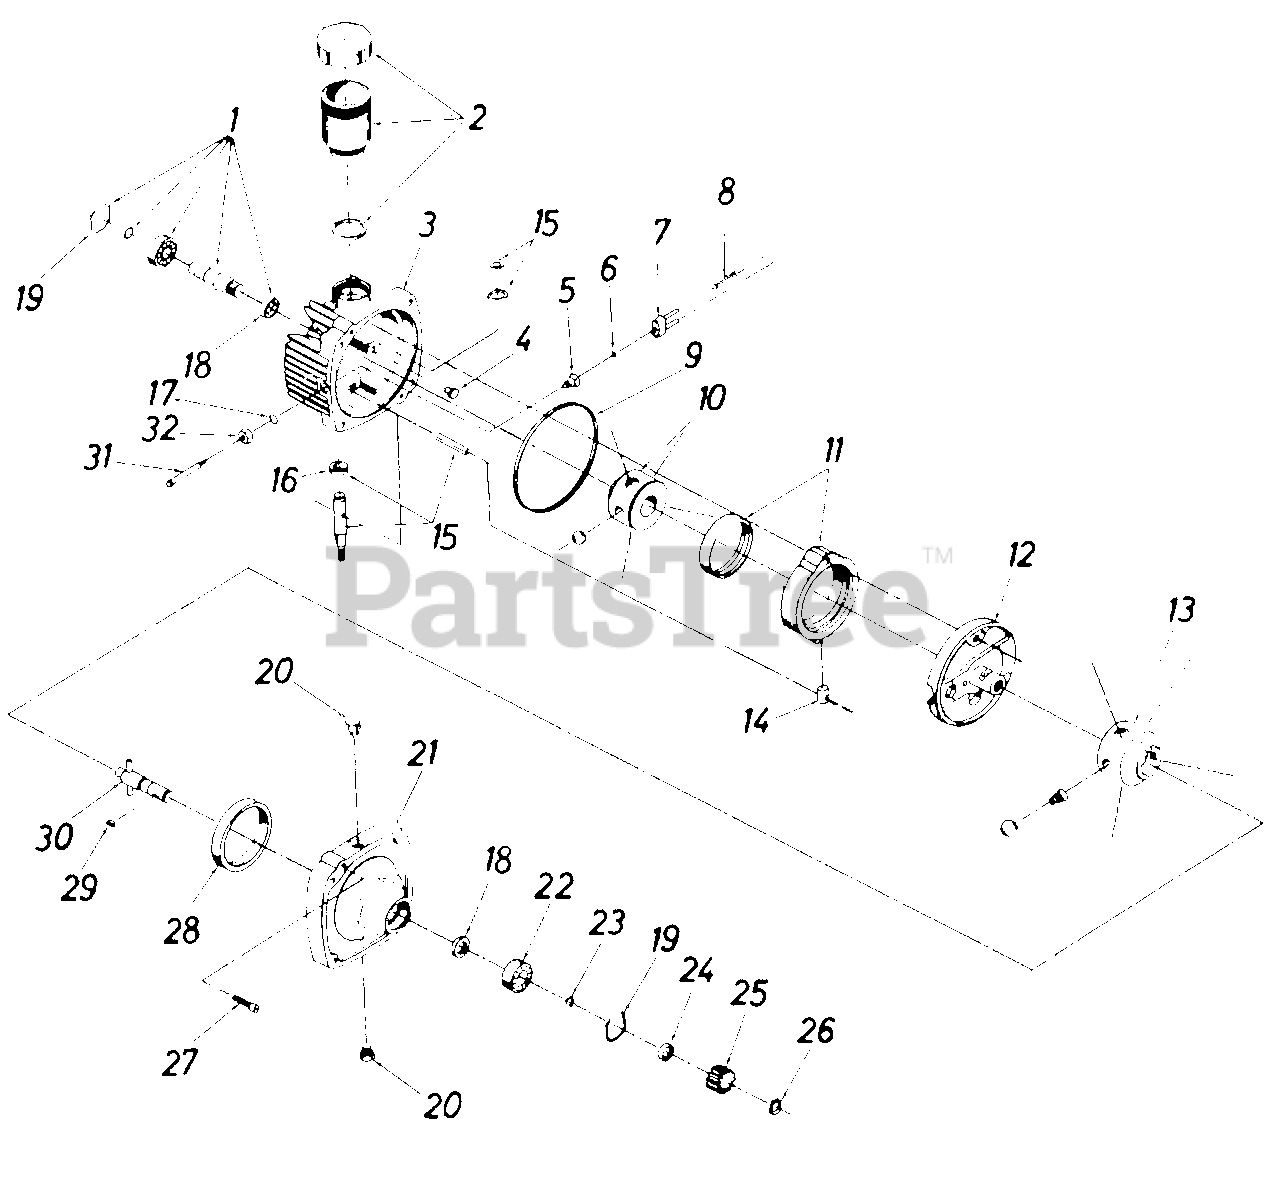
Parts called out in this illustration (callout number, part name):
1	Kit Input Shaft
2	Kit Reservoir
3	Kit Cover
5	O-Ring Fitting Guide Subassembly
7	Bracket Pins Subassembly
8	Valve Spring
9	Square Cut Seal Ring
10	Pump Rotor Ball Subassembly
11	Cam Ring Subassembly
12	Pintle Subassembly
13	Motor Rotor Ball Subassembly
14	Cam Ring Insert
15	Kit Control Shaft
16	Oil Seal
17	O-Ring .013
19	Retaining Ring
20	O-Ring Plug Subassembly
22	Ball Bearing
23	Snap Ring
25	Drive Gear (12 Teeth)
26	External Retaining Ring
27	Socket Hd. Scr. 5/16-18 x 1.25" Lg.
28	Motor Race
29	Woodruff Key #3
30	Output Shaft Subassembly
31	Dump Valve Shaft
32	Nut Gasket Subassembly
